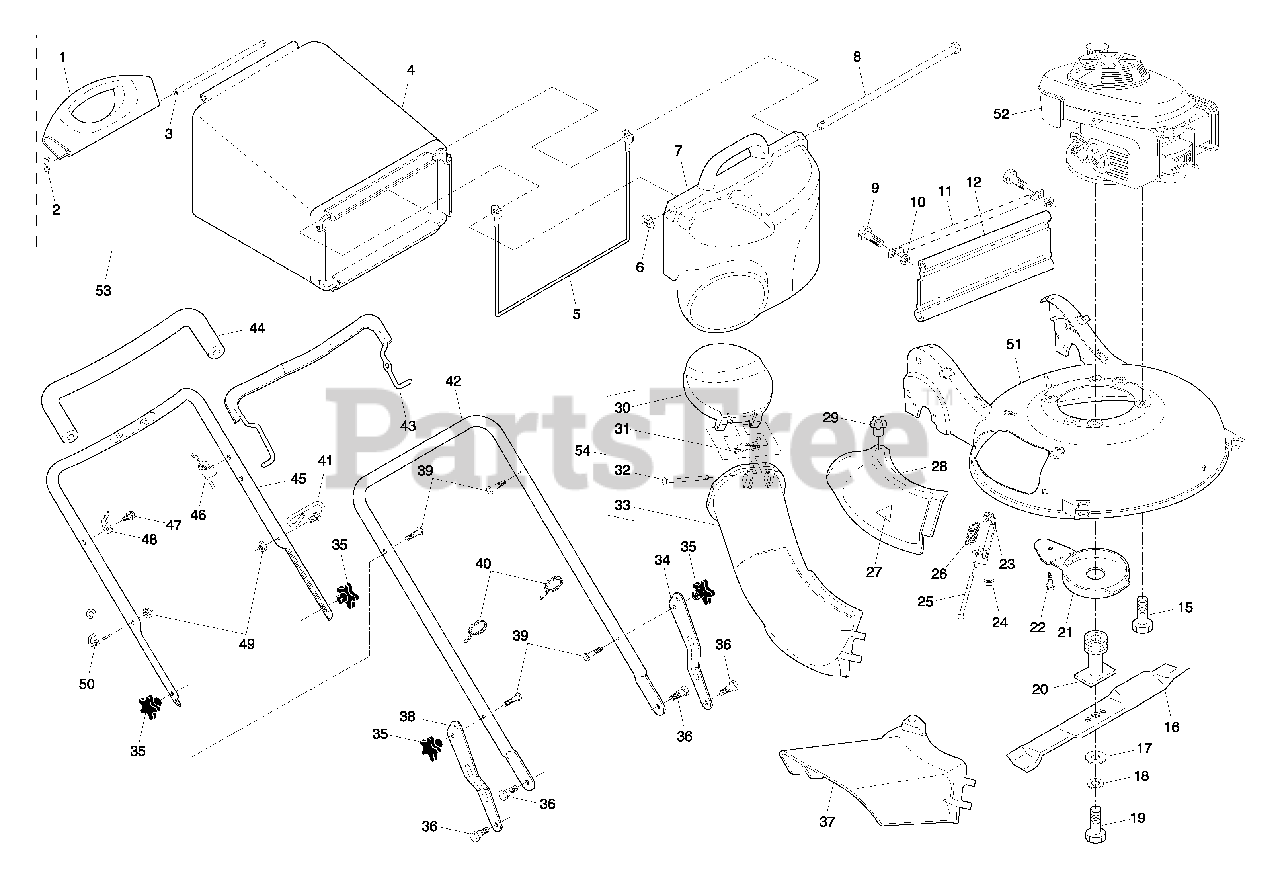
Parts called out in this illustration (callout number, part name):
1	Handle, Grassbag, Rear
2	Hairpin Cotter
3	Rod, Rear Handle, Grassbag
4	Grassbag
5	Frame, Grassbag
7	Door, Grassbag
10	Nut, Hex, Nylock 1/4-20
11	Tube, Rear Skirt
12	Skirt, Rear
15	Bolt, Engine Mounting
17	Washer, Hardened
18	Washer, Lock
19	Screw, Hex Head, Grade 8
20	Adapter, Blade
21	Debris Shield
22	Screw, Hex Head, Serrated
23	Mounting Bracket, Mulcher Door
24	Nut, Hex
26	Spring, Mulcher Door
27	Decal, Danger
28	Mulcher Door
30	Door, Discharge Chute
31	Spring, Door, Discharge Chute
32	Rod, Door, Discharge Chute
33	Discharge Chute, Plastic
34	Adjustment Bracket, Lower Handle, LH
36	Bolt, Shoulder
37	Deflector, Discharge
38	Adjustment Bracket, Lower Handle, RH
39	Bolt, Handle
40	Wire Tie
41	Bracket, Anti-Fold
42	Handle Assembly, Lower
43	Bail, Control
45	Handle Assembly, Upper
46	Cable, Engine Zone Control
48	Bracket, Upstop
53	Grass Catcher Assembly, Complete
54	Discharge Chute Assembly, Complete
